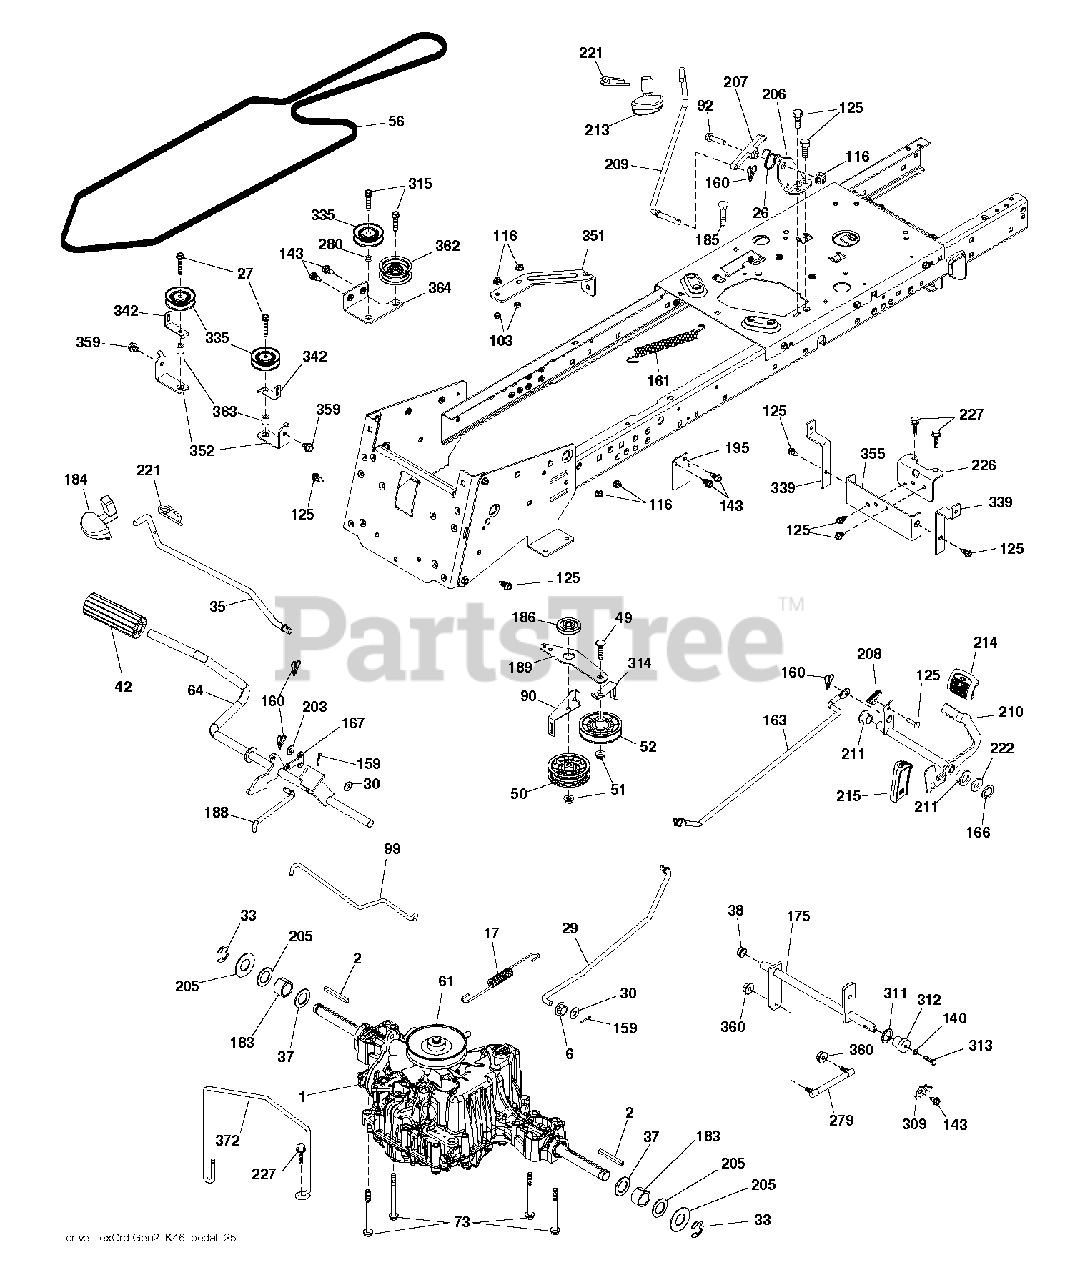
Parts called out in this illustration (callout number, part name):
2	SQUARE KEY
6	GROMMET T
26	SPRING.RETURN.CRUISE
33	E-RING LT
35	Parking Brake Rod, GT Husq
37	WASHER.HARDENED
38	NYLINER SNAP 5/8" ID
42	PEDAL COVER T
49	BOLT
50	IDLER.FLAT.910.OFFSET
51	NUT LOCK FLG 3/8-16 UNC
52	IDLER.V-GROOVE.910.OFFSET
64	SHAFT.ASM.PEDAL.BRK.CNTR
73	BOLT HEX 5/16-18 GR 5
92	BOLT
103	JAM NUT TI
116	NUT LOCK HEX FLANGE 5/16-18
125	SCREW
140	LOCKWASHER
159	COTTER PIN
160	RETAINER CLIP
161	SPRING, RETURN LT
166	NUT.PUSH.625
167	LATCH.BRAKE.SPRING
183	SPACER AXLE
184	Parking Brake Handle, Black
186	SPACER.RETAINER
188	LINK.CLUTCH.GROUND.DRIVE
203	WASHER
207	Control Cruise Latch, Tex
208	GEAR.SECTOR.CONTROL.CR
209	ROD.CONTROL.CRUISE.GT.
210	ROCKER.ASM.PEDAL.CONTR
211	BEARING.NYLON
213	KNOB.CONTROL.CRUSIE.HU
214	PAD PEDAL FORWARD
221	RETAINER.SPRING.CLIP.H
222	WASHER 21/32 X 1-1/4 X 10 GA.
226	BRACKET.MOUNT.TORQUE.K46.TLT
227	SCREW
309	PLATE FASTENING LT
311	WASHER NYL
315	BOLT.5/16-18X1.25
335	PULLEY.V-IDLER.
359	SCREW LT.3/8-46X5/8
372	RB KEEPER.BELT.TRXL.CRD2.K46
